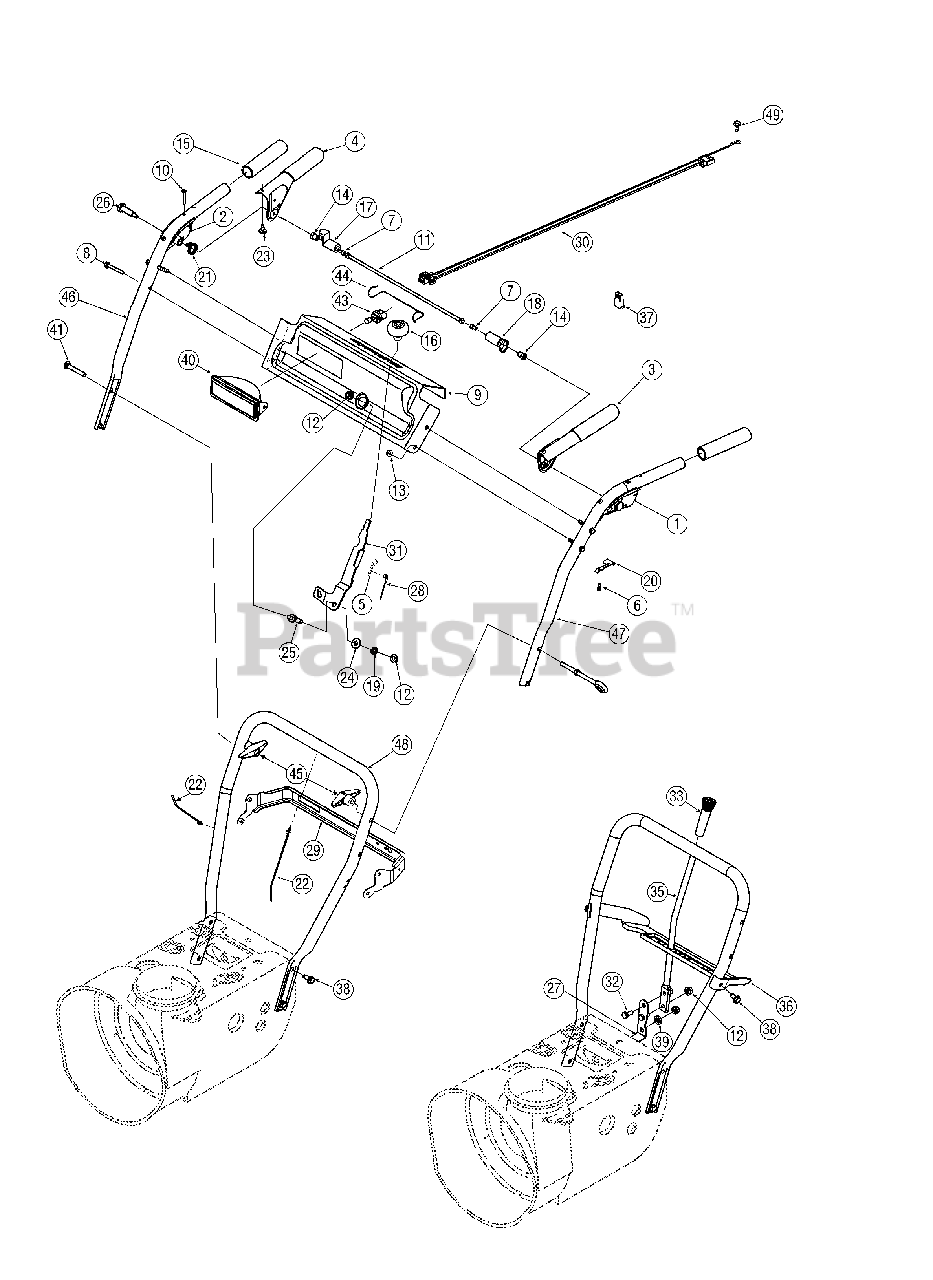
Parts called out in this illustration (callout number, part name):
1	LH Clutch Lock Handle Ass’y
2	RH Clutch Lock Handle Ass’y
3	Engagement Handle Assembly LH, Black
4	Engagement Handle Assembly RH, Black
5	Cotter Pin
6	Screw No. 8-16 x .50
7	Screw, 1/4-20 x 1.5
8	Hex TT Screw, 1/4-20 x 1.5
10	Oval C-Sunk Hd Screw 10-24 x 1.375
12	Flange Locknut 5/16-18 Gr. F Nylon
13	Flange Locknut 1/4-20 Gr. F Nylon
14	Hex Nut 1/4-20
18	Clutch Lock Cam
19	Compression Spring .38 ID x .88 Lg
20	Spring: Clutch Lock
21	Torsion Spring .8156 x .3038
22	Cable Tie Push Mt.
23	Rubber Bumper
24	Flat Washer .38 ID x .87 OD x .09
25	Shoulder Screw 1/4-20 x 1.345
26	Shoulder Screw .437 x 1.345:1/4-20
27	Shift Lever Spring
28	Selector Speed Cable
29	Panel Bracket
30	Wiring Harness
31	Shift Lever
32	Screw, 5/16-18 x .625
37	Alternator Cap (models w/o light only)
38	Screw, 5/16-18 x .75
39	Flat Washer -Special
40	Lens Assembly
41	Carriage Bolt 5/16-18 x 2.25
43	Lamp Halogen 12V, 27W
44	Lens Retainer
45	Handle Knob Assembly
46	Upper RH Handle - Black
47	Upper LH Handle - Black
48	Lower Handle - Black
49	Hex Wash S-Tapp Scr 1/4-20 x .50
